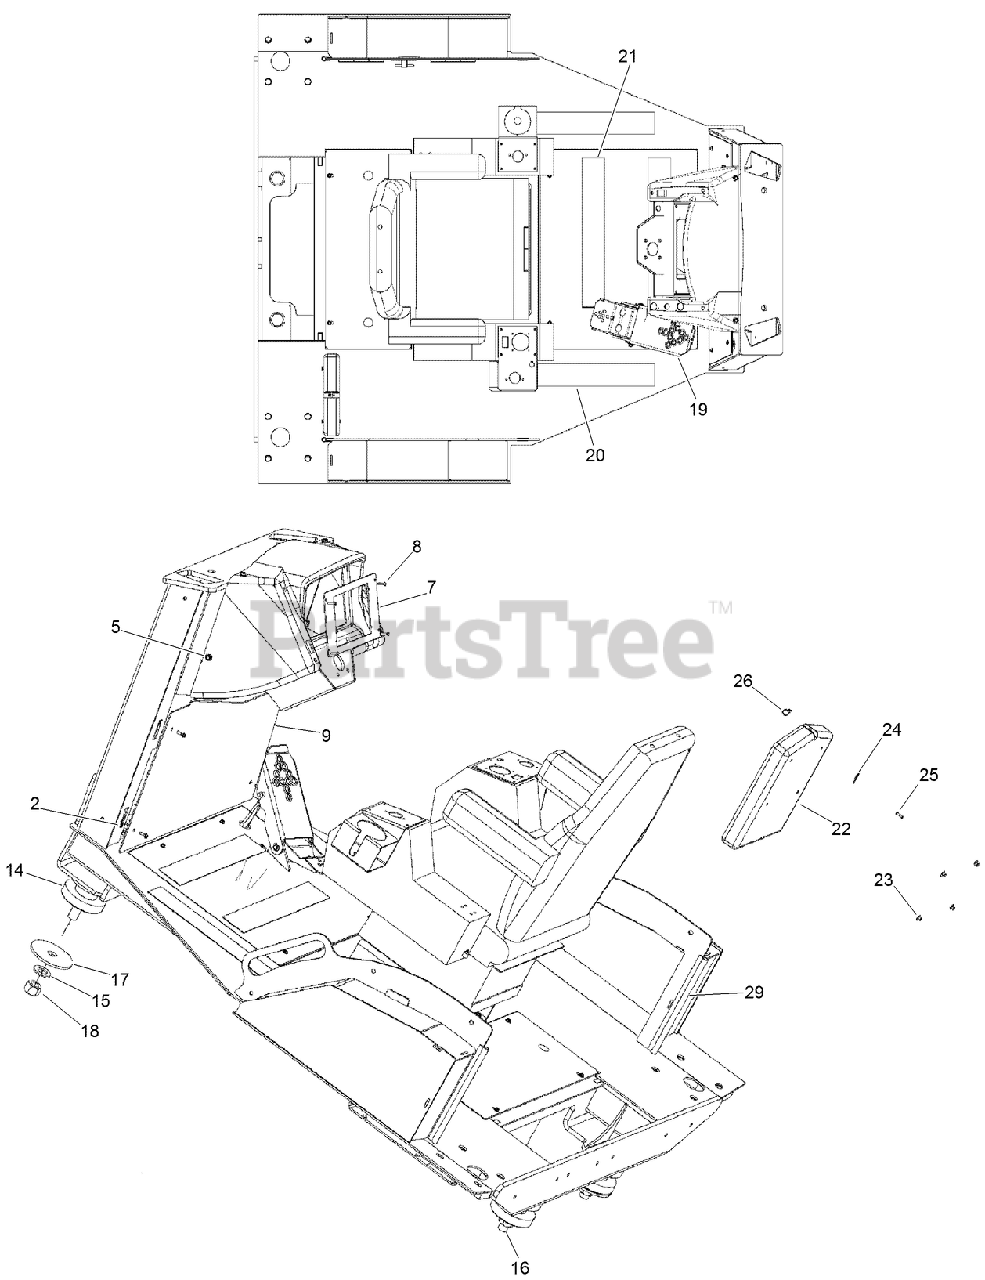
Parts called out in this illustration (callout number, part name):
5	SCREW-HH
7	PLATE - Display Mount
8	SCREW-HH
9	PLATE - Kick Panel
14	MOUNT-RUBBER
16	BOLT-HH
17	WASHER-SNUBBER
19	PEDAL ASM
20	TAPE-ANTI SKID, UPPER STEP
21	TAPE-ANTI SKID, LOWER STEP
22	HOLDER-MANUAL, OPERATOR
24	LANYARD
25	POST-MANUAL
26	STRAP-TIE, NYLON
29	SEAL-Hood
